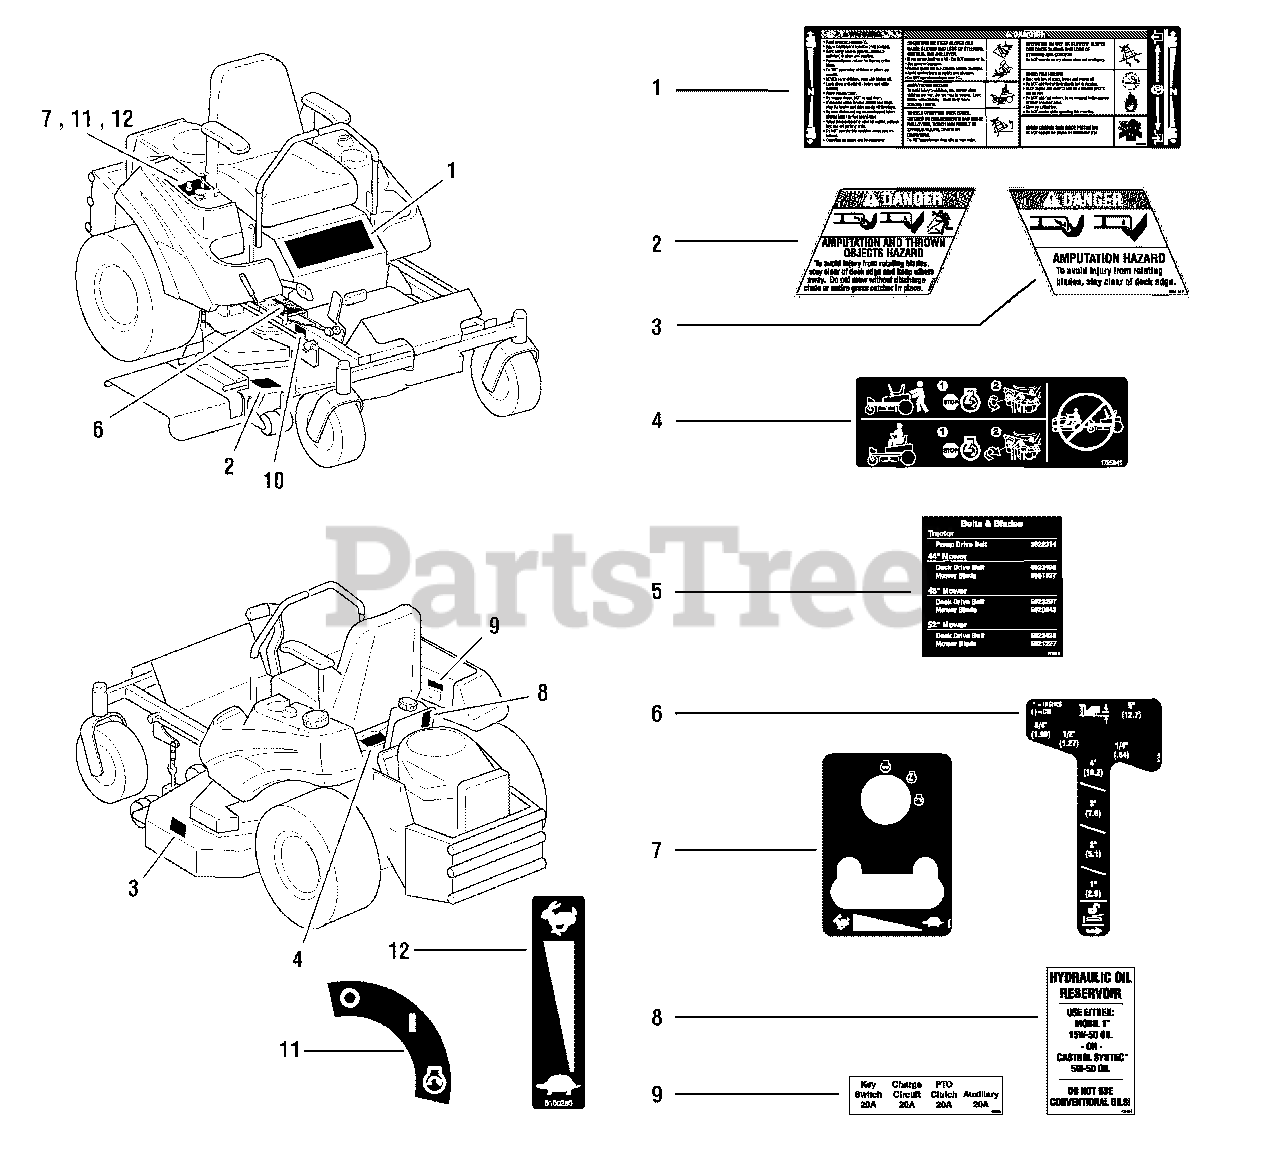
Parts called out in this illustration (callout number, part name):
1	DECAL, Main
2	DECAL, Danger (Chute In Place)
3	DECAL, Danger (Hand Under Deck)
4	DECAL, CZT Hydro Release
5	DECAL, Belt & Blade (located under seat mount)
6	DECAL, Height of Cut
7	DECAL, Ignition / Throttle
8	DECAL, Oil Reservoir
9	DECAL, Fuse Location
10	DECAL, ID Plate
11	DECAL, Ignition Switch
12	DECAL, Throttle Control
